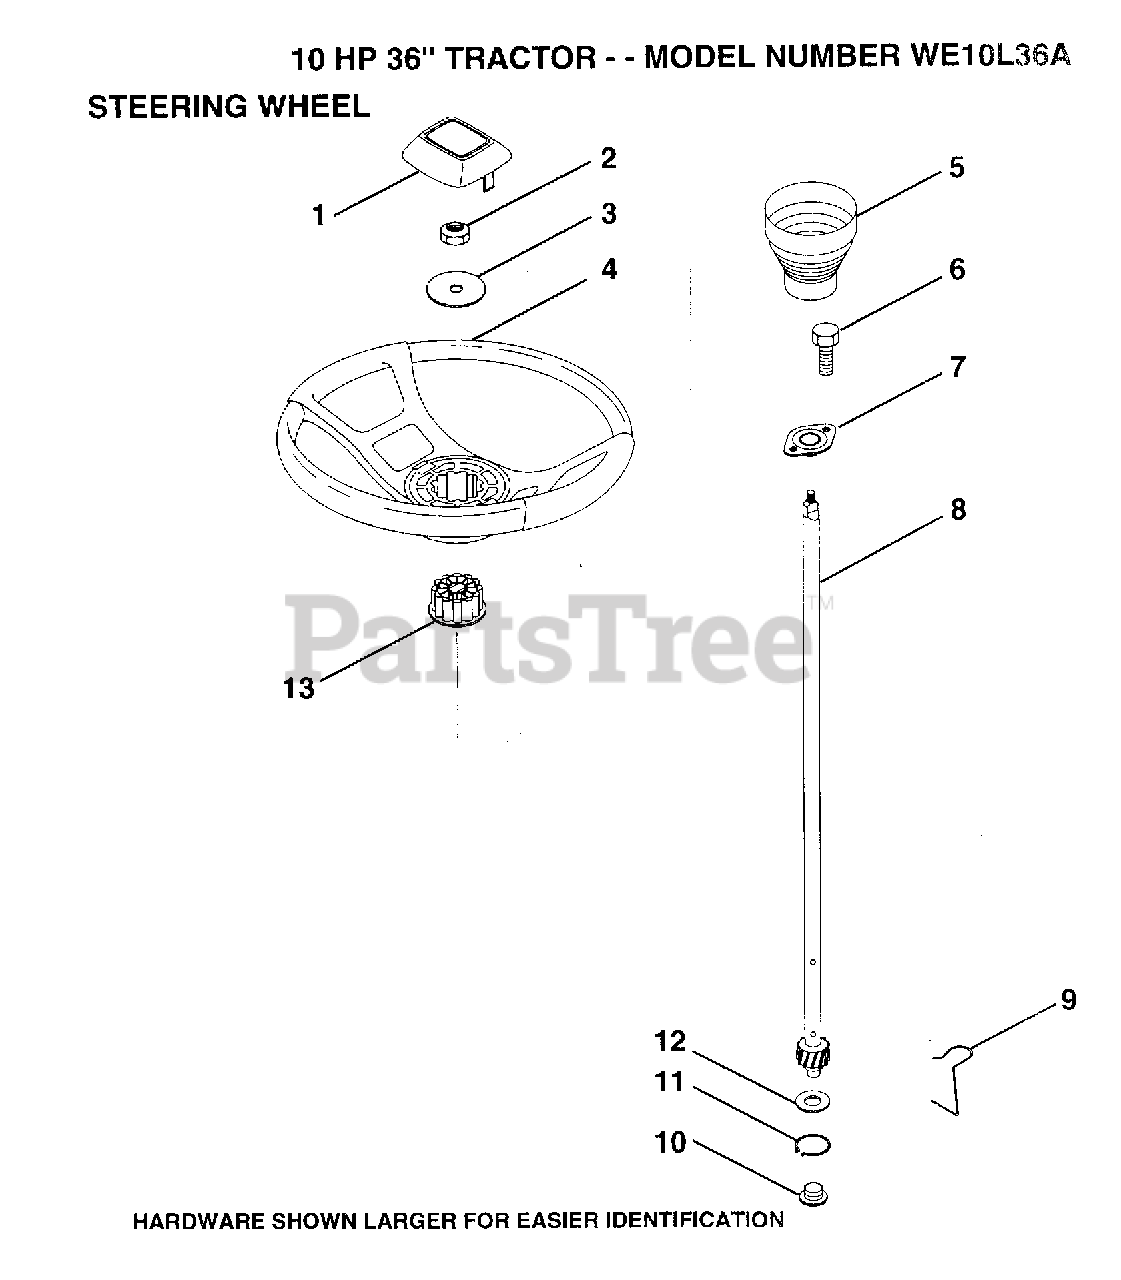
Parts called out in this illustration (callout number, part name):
1	ST WHL INSERT CAP
2	GRIPCO NUT
3	WASHER T
5	SLEEVE STEERING
9	STEERING CLIP
10	BUSHING STEER LWR
11	RING
12	WASHER LT
13	ADAPTER-WHEEL LT
